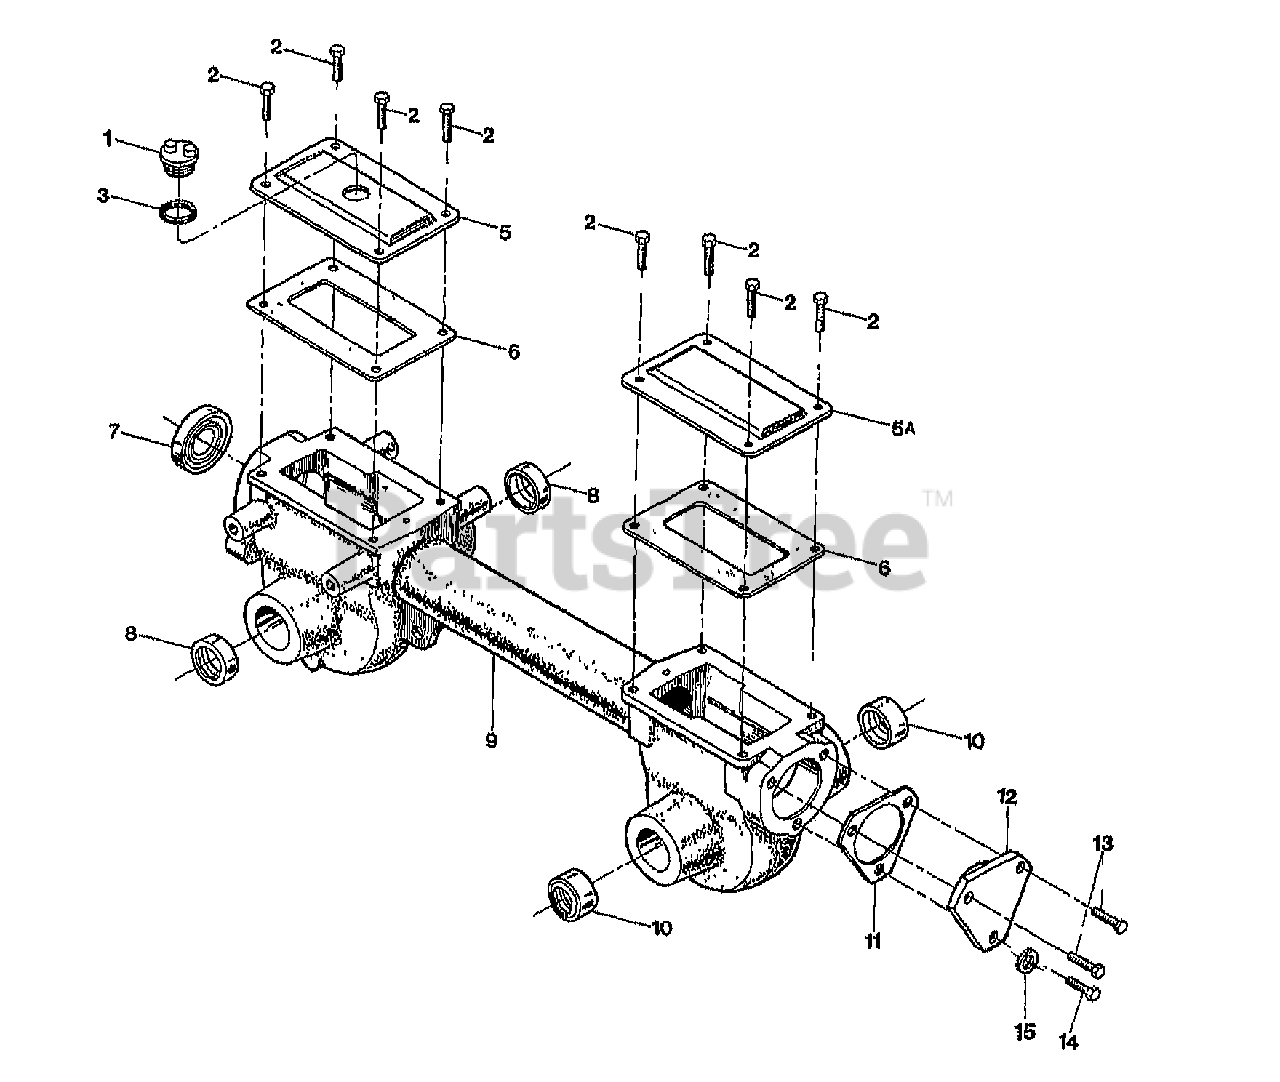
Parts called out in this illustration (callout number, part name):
1	PLUG-OIL FILL 3/4-10
2	SCR-HFLK 5/16-18X.62 G5ZP
3	GASKET-O RING .674 I.D.
5	COVER-TRANS FRNT PNT
5A	CVR-TRANS REAR PNT
6	GASKET-GEAR HSG
7	SEAL-OIL DRIVESHAFT
8	SEAL-OIL WHEELSHAFT
9	TRANSMISSION-MACH
9	HSG-TRANS T/B TUFFY {12155}
10	KIT-OIL SEAL TUFFY
11	GASKET-BEARING CAP .010
11	GASKET-BEARING CAP .030
12	CAP-REAR BEARING-PM
13	SCR-HFLK 5/16-18X1.00 ZP
14	SCR-HFLK 5/16-18X.75 ZP
15	WASHER-LK .312 ZP
